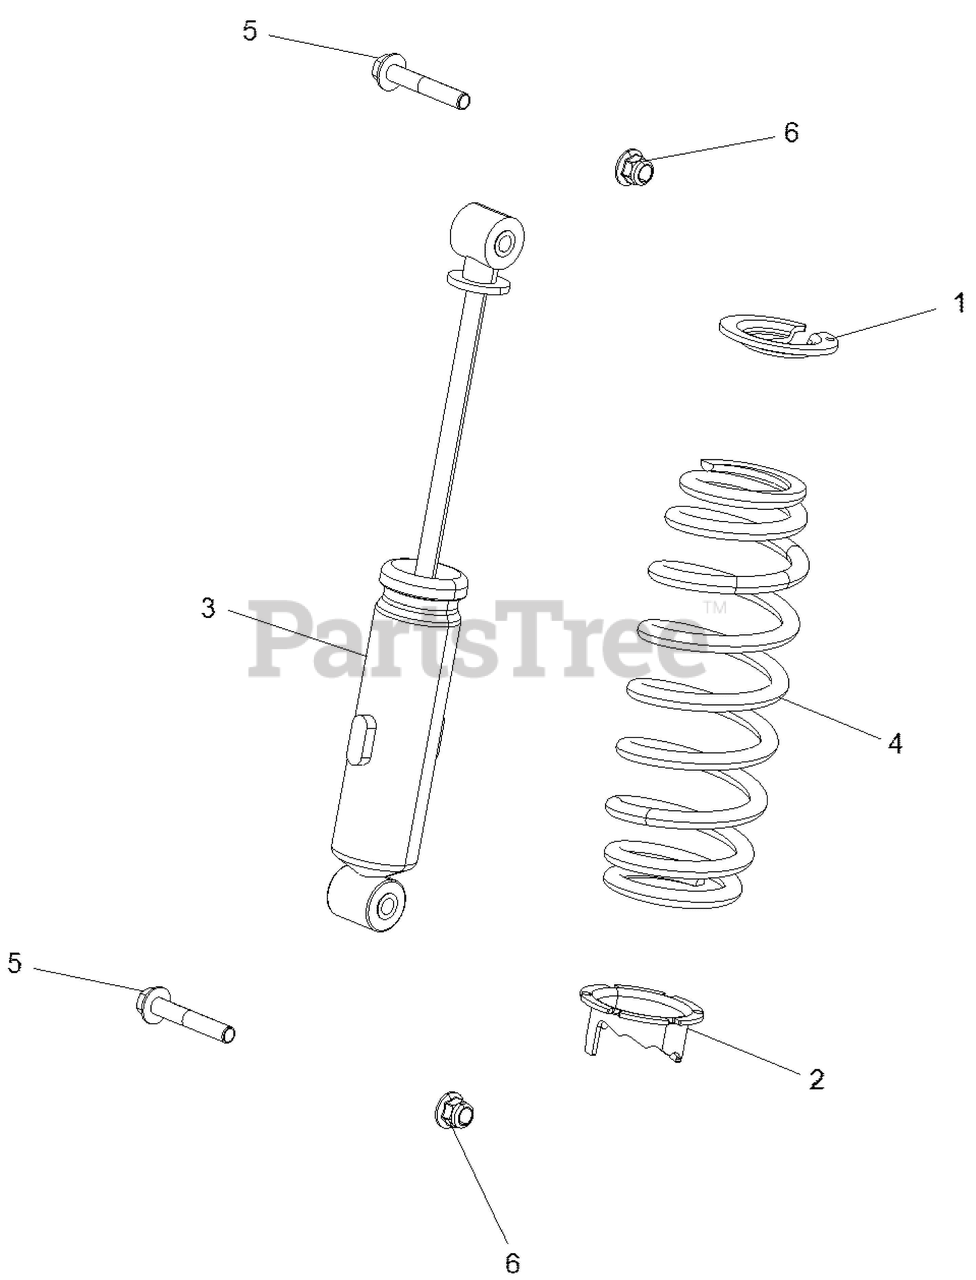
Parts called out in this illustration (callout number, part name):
1	RETAINER-SPRING,STEEL
2	CAM-ADJUSTING,SPRING,STEEL
3	SHOCK-FRONT,SPLY
4	SPRING, FRONT, MATTE BLACK
5	SCR-HXFL-M10X1.25X60 10.9 ZOD
6	NUT, FLANGE, NYLOK
